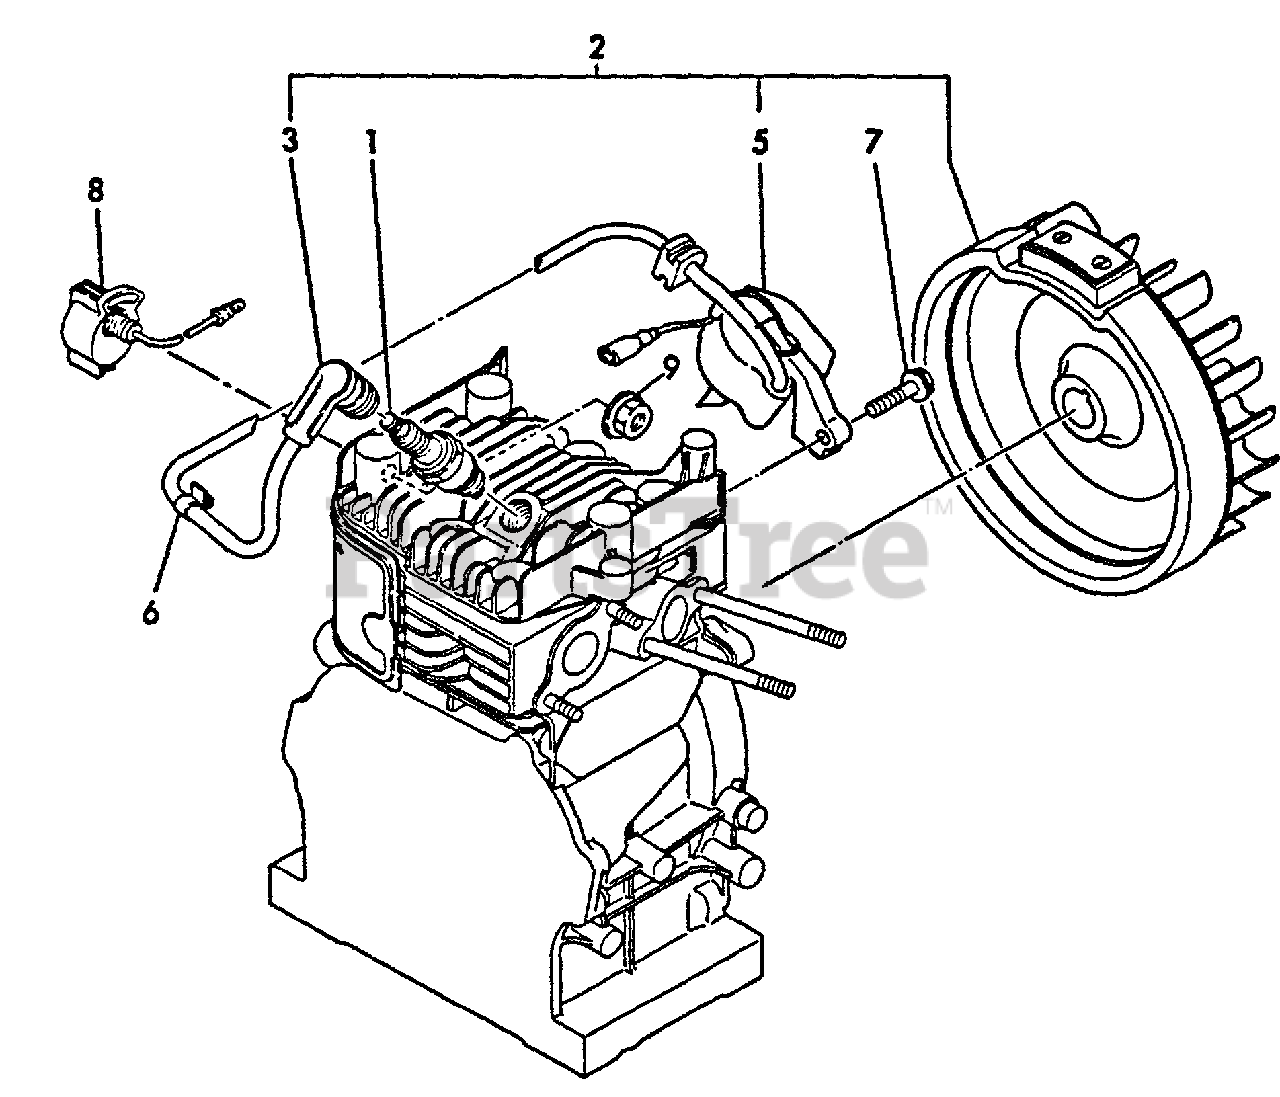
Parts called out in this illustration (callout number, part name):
1	SPARK PLUG
2	FLYWHEEL
3	CAP, PLUG
5	COIL, IGNITION
6	CLAMP
7	BOLT - 6×30
8	IGNITION SWITCH ASSY
9	U-NUT M8
